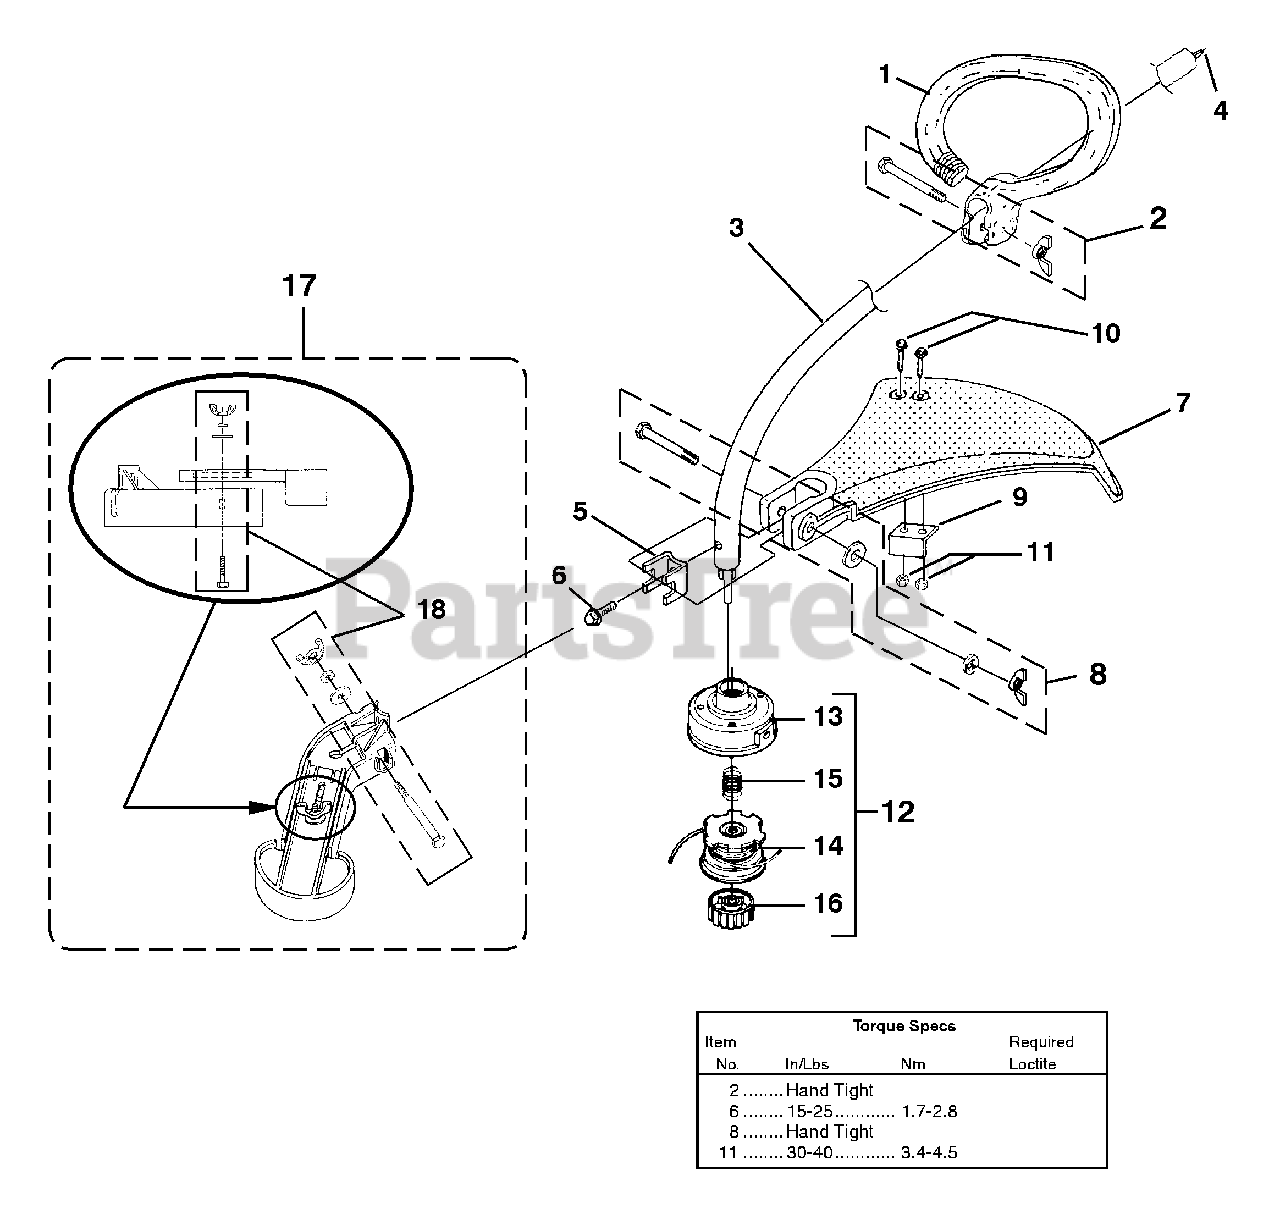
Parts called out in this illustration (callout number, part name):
1	HANDLE ASSY.-Front
2	FASTENER PARTS KIT
3	DRIVESHAFT HOUSING ASSY.
4	SHAFT-Flexible
5	CLAMP
6	SCREW-T.F. Hex Hd. (10-32 X 3/8")
7	DEFLECTOR & BLADE KIT (55 Deg.)
8	FASTENER PARTS KIT
9	BLADE-Cut-Off
10	SCREW-Mach. Hex Hd. (10-24 X 7/8")
11	NUT-Hex (10-24)
12	STRINGHEAD-Complete
13	HOUSING & EYELET (Dual Line)
14	SPOOL & STRING (.080" Line)
15	SPRING-Compression
16	RETAINER-Spool (RH Thread, Black)
17	EDGER GUIDE KIT
18	FASTENER PARTS KIT EDGER
